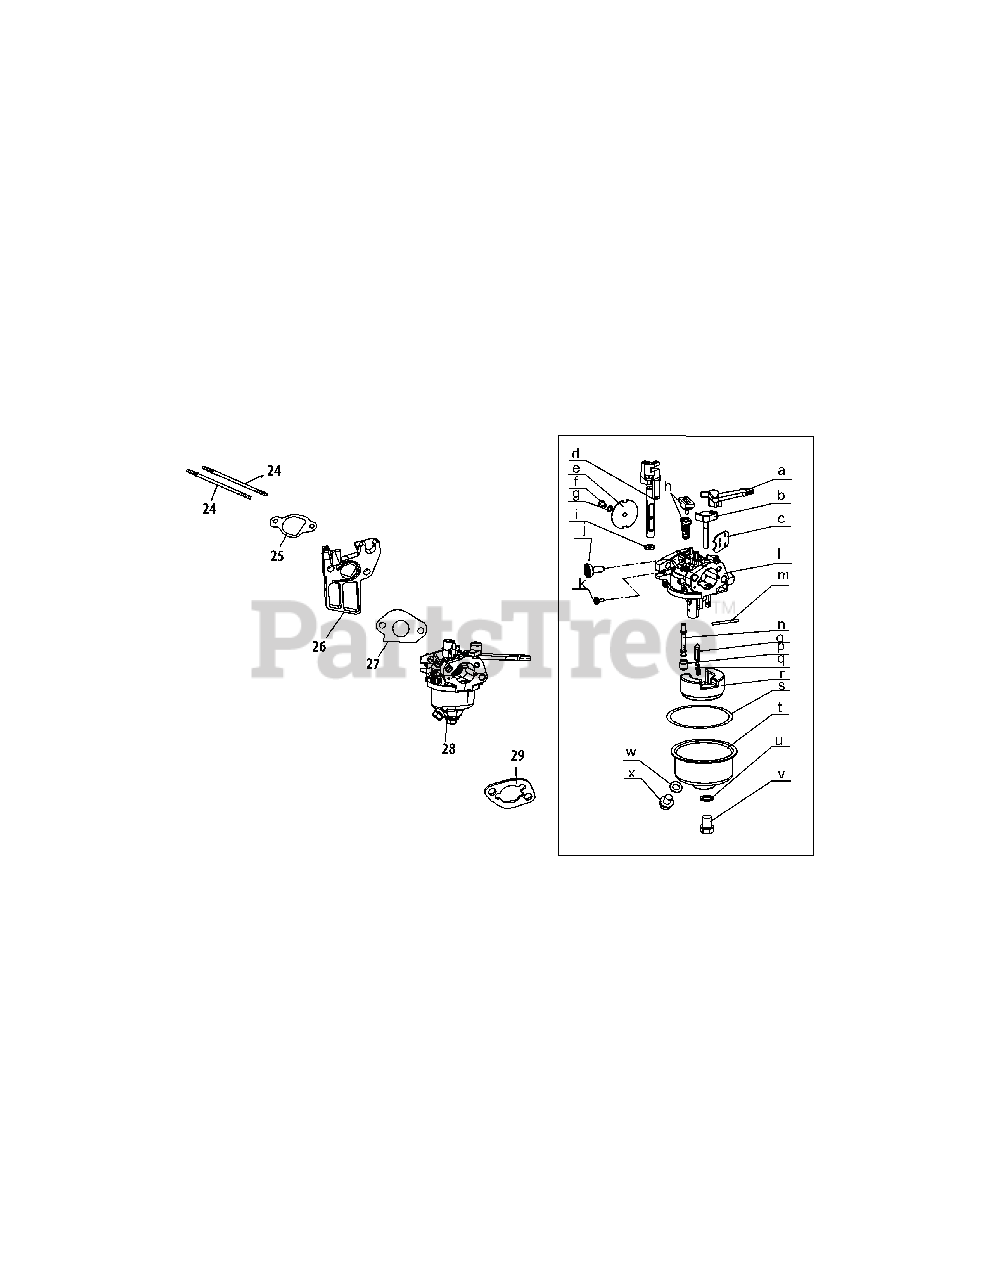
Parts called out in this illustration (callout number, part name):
24	Carburetor Stud M6×110
25	Carburetor Insulator Gskt
26	Carburetor Insulator Plate
27	Carburetor Gasket
28	Carburetor Assembly
29	Carburetor Gasket Plate
